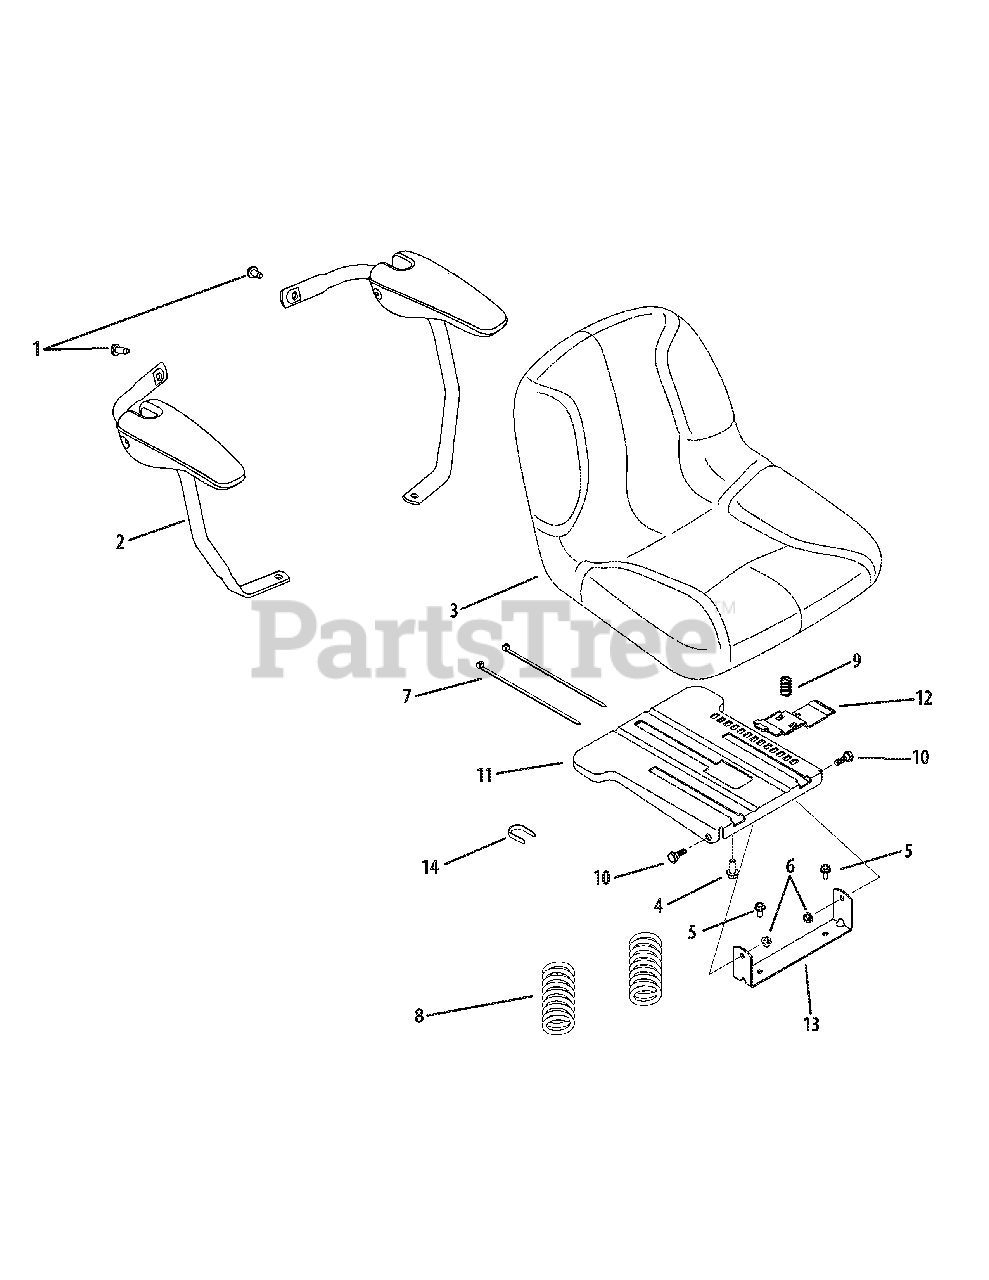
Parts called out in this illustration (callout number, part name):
1	Screw, 5/16-18 x .750
4	Screw, Hex Flange, 3/8-16 x .875
5	Screw, Hex Washer, 5/16-18 x .750
6	Nut, Flange Lock, 5/16-18
7	Tie, Cable
8	Spring, Comp., 1.71 x 3.735 x .238
9	Spring, Comp., .68 x 1.065 x .055
10	Screw, Shldr., 5/16-18 x .437 x .268
11	Bracket, Seat Moun
12	Lever, Seat Adjust
13	Bracket, Seat Pivot
14	Clip, Ret. Switch
